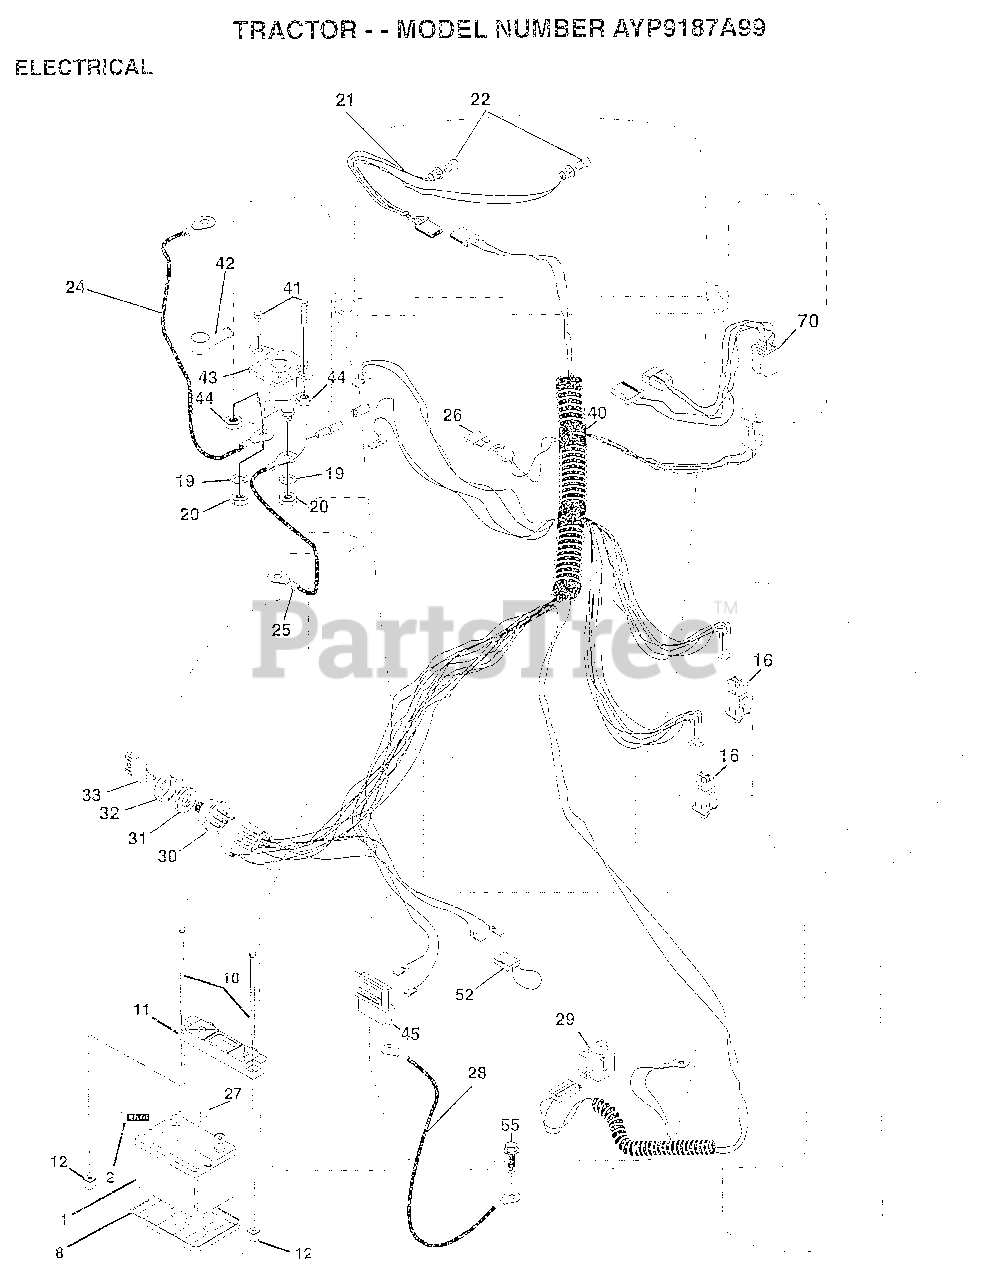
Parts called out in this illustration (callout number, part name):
2	BOLT LT
8	"TRAY T, BATTERY"
11	HOLDDOWN BATTERY
16	SWITCH INTERLOCK
20	NUT
21	HARNESS.ASM.LIGHT W/4152J
22	HEADLAMP BULB
24	"CABLE T, BATTERY"
25	CABLE.6GA.22W/16W
26	FUSE.15 AMP
27	NUT
28	CABLE.GRND.6GA.21
29	SWITCH SEAT
30	SWITCH IGN 4POS
31	NUT IGNITION
32	COVER KEY SWITCH
33	KEY
40	HARNESS.IGNITION
41	BOLT HXHD FIN
44	NUT HXKEP 1/4X20
52	PROTECTION LOOP
55	SCREW LT
70	HARNESS.ENGINE.B&S
